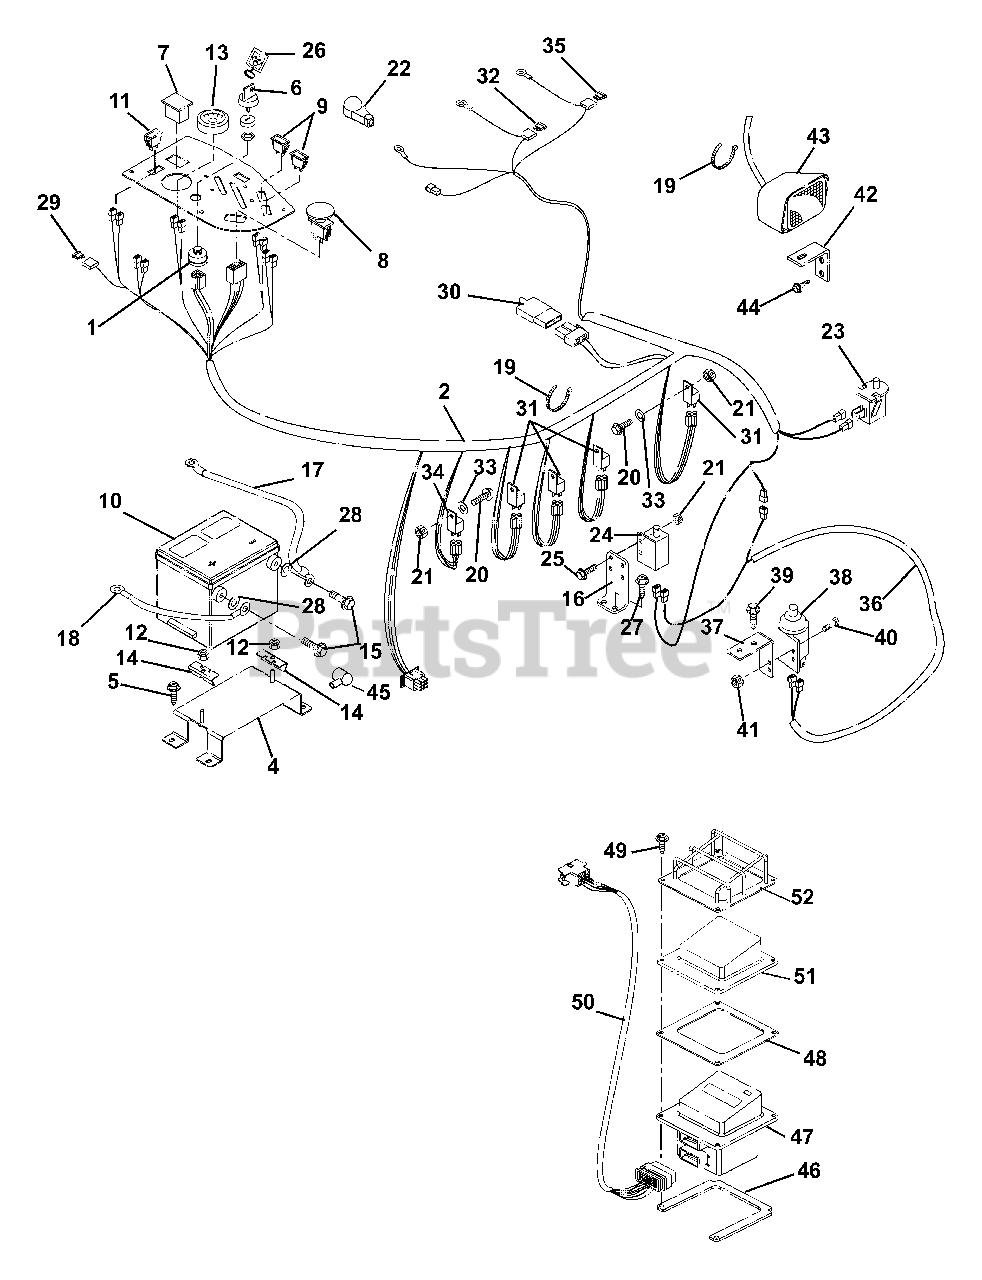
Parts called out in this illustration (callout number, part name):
1	Switch, Ignition (Diesel) (075, 076, 318, 319)
1	Switch, Ignition (073, 074)
2	Harness, Wiring (Diesel) (075, 076, 318, 319)
3	Harness, Wire (Gas) (073, 074)
4	Weldment, Battery Support
5	Screw-Tapping .38-16 x .75 Hex Washer Head
6	Key-with Cap
6	Ignition Key Set
8	Switch-Clutch With Retainer Ring
9	Light-Indicator Kit (075, 076, 318, 319)
9	Light-Indicator Kit (073, 074)
10	Battery with Tube
11	Switch, Light
12	Nut-Locking-Top-Flange .31-18
13	Gauge, Temperature
14	Bracket, Battery Hold-Down
15	Bolt-Hex .25-20 x .75 Grade 5
16	Mount, Safety Switch
17	Positive Cable (075, 076, 318, 319)
17	Positive Cable (073, 074)
18	Cable, Negative Battery (075, 076, 318, 319)
18	Ground Cable (073, 074)
19	Cable Tie
20	Screw-Machine 10-24 x .75 Hex Washer Head (075, 076, 318, 319)
20	Screw-Machine 10-24 x .75 Hex Washer Head (073, 074)
21	Nut-Locking-Nylon 10-24 With Insert (075, 076, 318, 319)
21	Nut-Locking-Nylon 10-24 With Insert (073, 074)
22	Eyelet Terminal Boot
23	Switch, Snap Mounting (N.O.)
24	Switch-Single Pole
25	Screw-Machine 10-24 x .75 Hex Washer Head
26	Key Chain
27	Screw-Tapping .25-20 x .50 Hex Washer Head
28	Washer-Flat-Steel .406 x 1.00 x ..083
29	Fuse, 15 Amp
30	Diode, Connector Shell
31	Relay
32	Fuse, 30 Amp
33	Washer-Flat-Steel .25 x .562 x .049 (075, 076, 318, 319)
35	Fuse, 50 AMP (Maxi Fuse)
35	Fuse, 25 Amp
36	Harness, Wire Adapter CE (318, 319)
37	Mount- Switch (318, 319)
38	Switch-Single Pole (N.O.) with Cover (318, 319)
39	Screw-Tapping .31-18 x .50 Hex Washer Head (318, 319)
40	Screw-Machine 10-24 x .75 Hex Washer Head (318, 319)
41	Nut-Locking-Nylon 10-24 with Insert (318, 319)
42	Bracket, Headlight Mounting
43	Headlight
44	Screw-Tapping .38-16 x .50 Hex Washer Head
45	Boot, Eyelet Terminal
46	Spacer, Enclosure Mounting (Bottom)
47	Assembly, Eye-Q
48	Gasket, Eye-Q
49	Screw, Machine 10-24 x 1.0 Slotted Pan Black
50	Harness Jumper (Eye-Q)
51	Guard, Element
52	Guard, Vinyl Eye-Q
